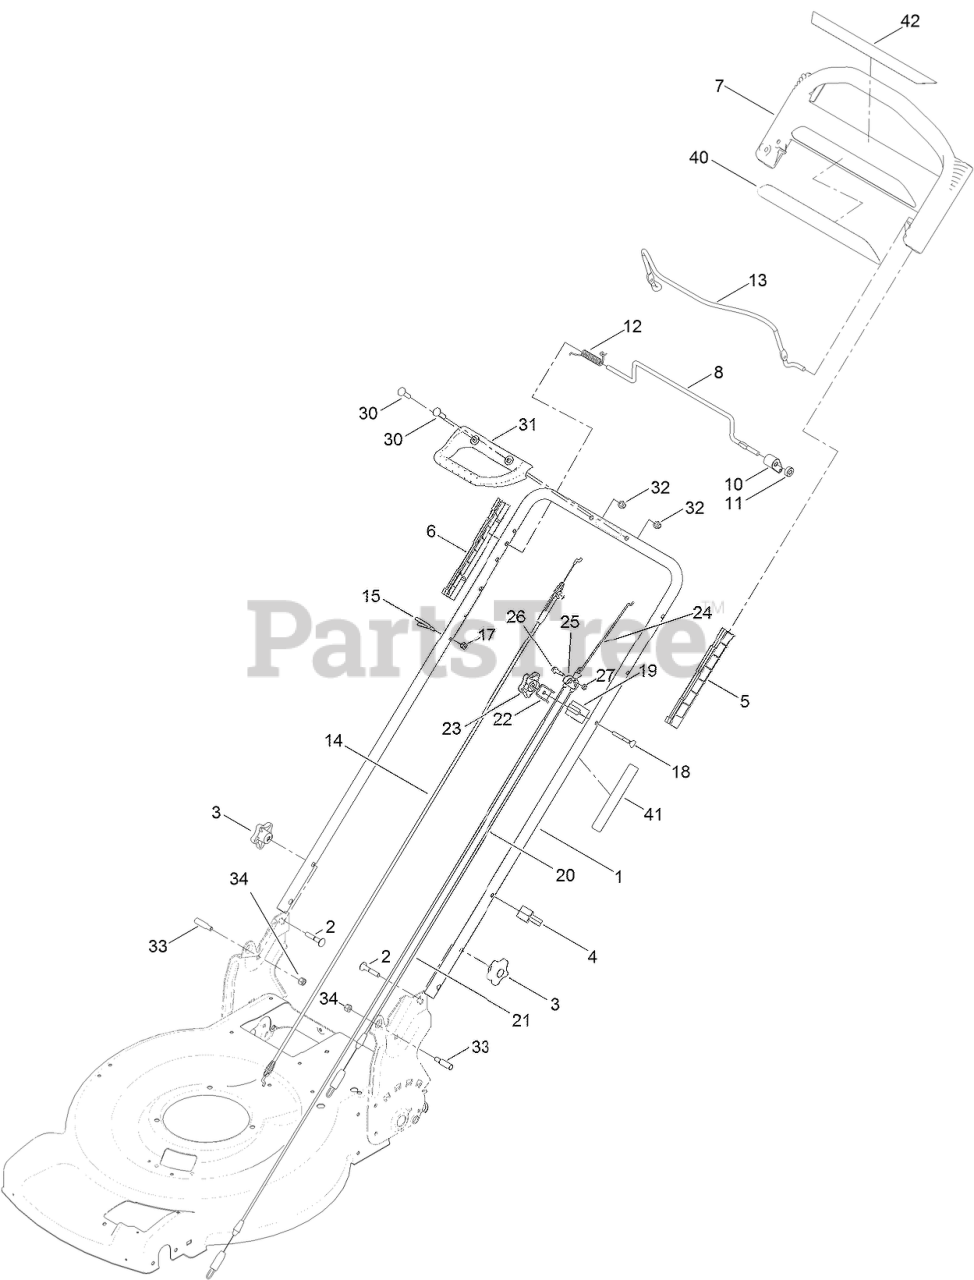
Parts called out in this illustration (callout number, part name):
2	SCREW-CARR
3	KNOB-HANDLE
4	GUIDE-CABLE
5	GUIDE-LH
6	GUIDE-RH
7	HANDLE-CONTROL
8	BAR-CONTROL, TRACTION
10	LEVER-TRACTION
11	SPACER
12	Spring-Torsion
13	BAIL-BRAKE
14	CABLE-BRAKE
15	GUIDE-ROPE
17	NUT-LOCK, NI
18	SCREW-HANDLE
19	MOUNT-CABLE, TRACTION
20	CABLE-TRACTION, FRONT
21	CABLE-TRACTION, REAR
22	CLAMP-CABLE
23	KNOB-HANDLE, LOCKING
24	LINKAGE-EQUALIZER
25	YOKE-CABLE
26	SCREW-SHOULDER
27	NUT-LOCK, NI
30	BOLT-CARRIAGE
31	HANDLE-ASSIST, TRACTION
32	NUT-ACORN
33	BOLT-SHOULDER
34	NUT-LOCK, NI
41	DECAL-TRACTION, ADJUST
42	DECAL-ASSIST, TRACTION
